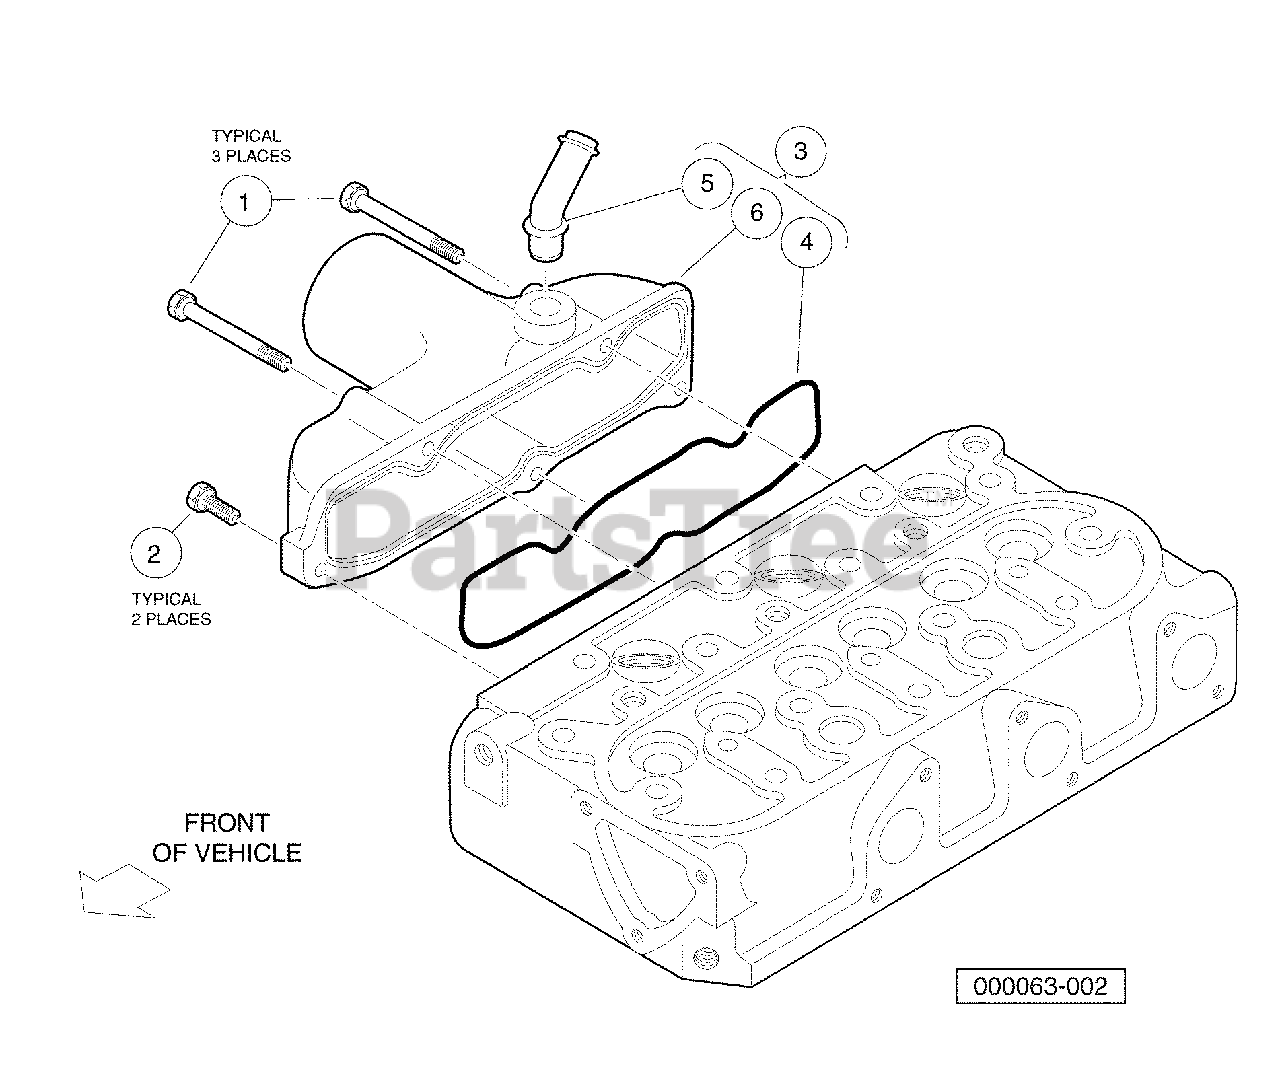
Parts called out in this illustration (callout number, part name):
1	Bolt, M6 X 1 X 45
2	Bolt, D722 Intake Manfld Lower
3	Assembly, Intake Manifold
4	Gasket, Intake Manifold
5	Pipe, Breather
6	Manifold, Intake
